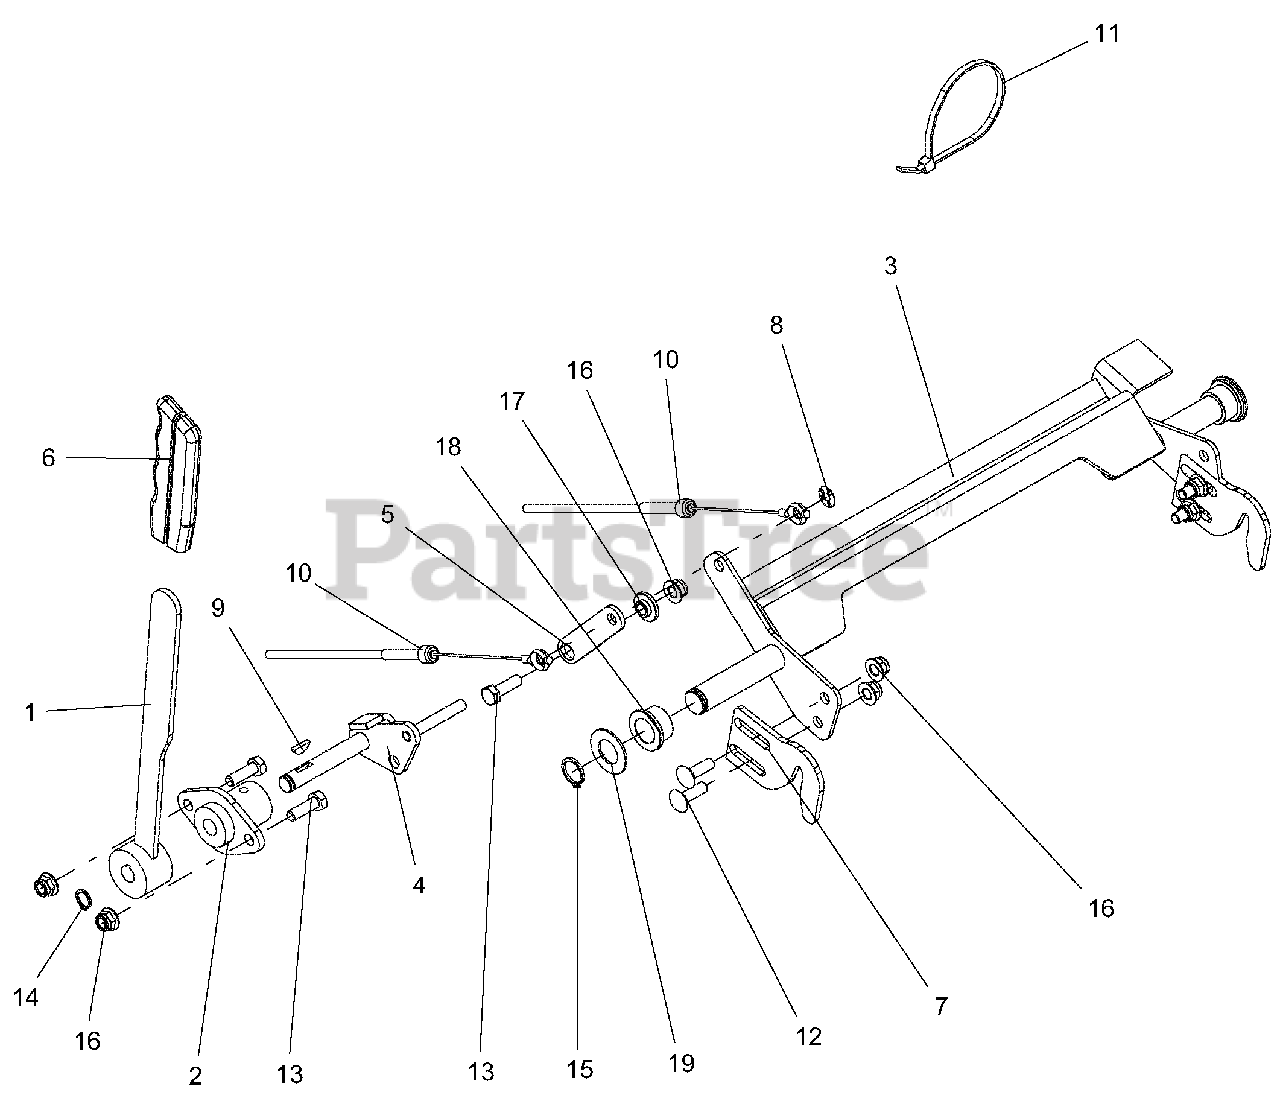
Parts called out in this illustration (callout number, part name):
1	WLDMT, PARKING BRAKE ARM
2	BSHG, FLANGE .500 ID
3	WLDMT, PT100 NEUTRAL LOCK
4	WLDMT, PARK BRAKE ARM
5	PLATE, NEUTRAL INTERLOCK
6	GRIP, PARKING BRAKE (YELLOW)
7	NEUTRAL, LOCK LATCH-BLACK
8	NUT, PUSH .312
9	KEY, WDRF .13x.63 HRD#5 GM124545P
10	CABLE, BRAKE ACTUATING
11	CABLE, TIE 5.50 LG
12	BLT-RDHDSQSHNK .31-18X1.00 G5 Y
13	BLT-HEX .31-18X1.00 GR5 YWZC
14	RG-RTNG-EXT .500x.050
15	RG-RTNG-EXT .750x.078
16	NUT-LK-NYL-FLG .31-18 YWZC
17	BSHG, FLG .325X.499X.26X.88
18	BSHG, FLG .750X1.00X.625X1.25
19	WSHR-FL-STL .755X1.375X.062 YWZC
